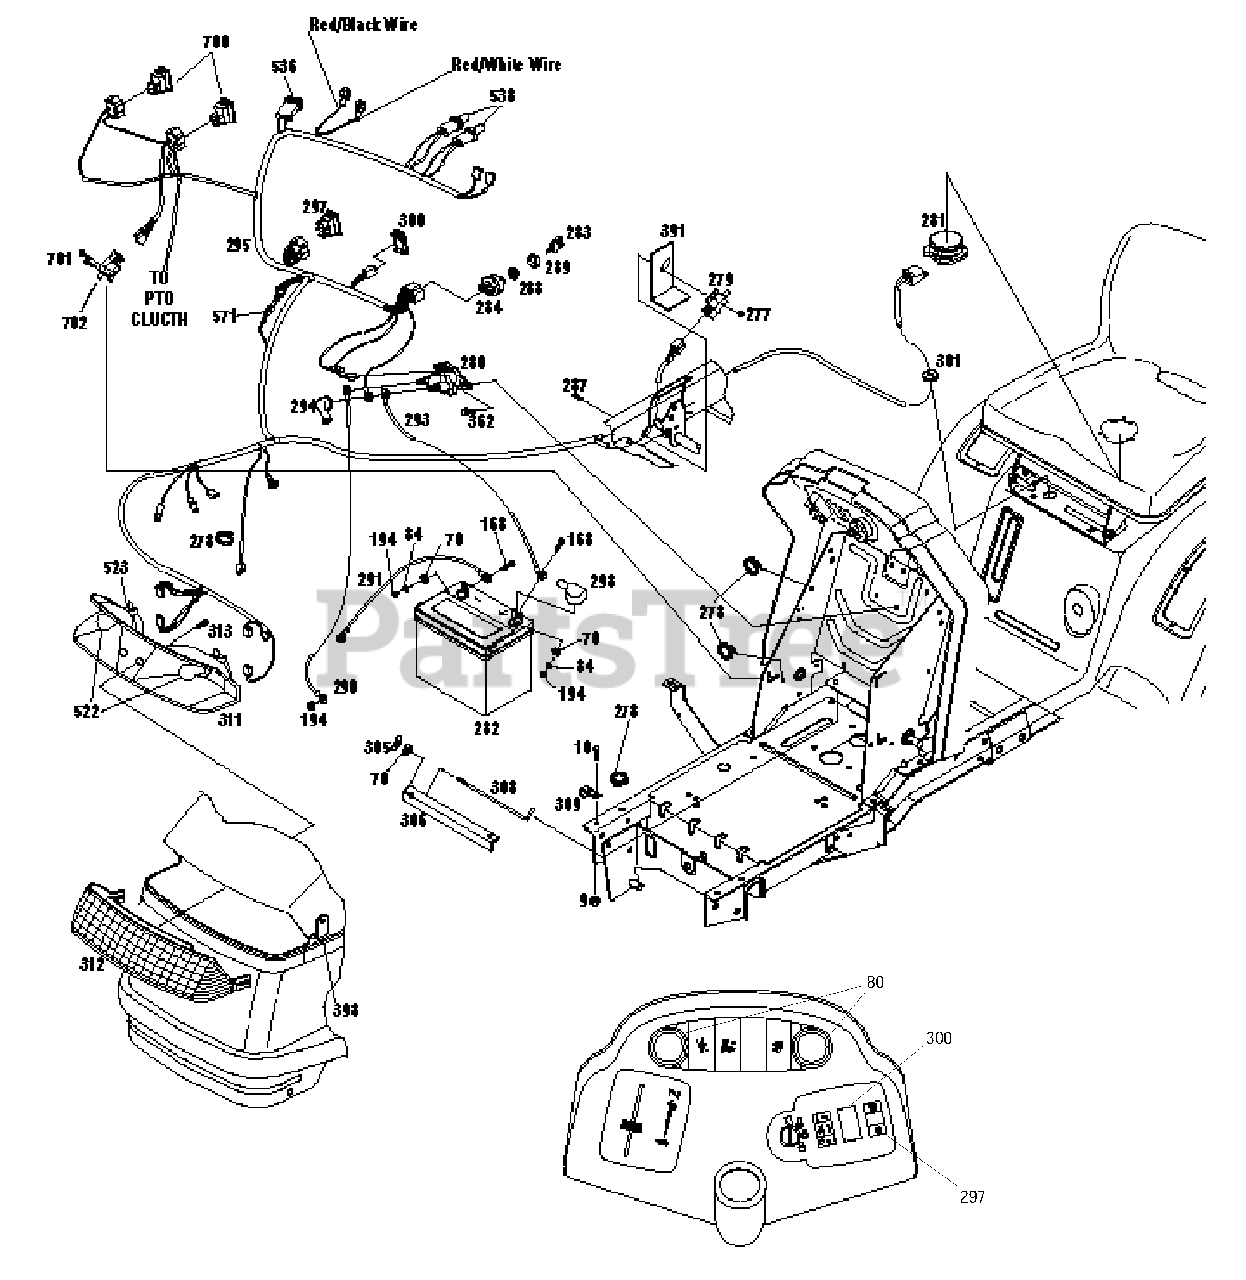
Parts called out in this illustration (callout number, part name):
9	Flange Nut, 5/16-18
10	Hex Head Screw, 5/16-18 x 3/4
70	Flat Washer, 1/4
84	Lockwasher, 1/4 SAE
168	Hex Head Screw, 1/4-20 x 3/4
194	Hex Nut, 1/4-20
277	Keps Nut, #10-24
278	Cable Tie
279	Push-Button Switch
280	Solenoid
281	Seat Switch
282	Battery
284	Ignition Switch
287	Sems Screw, #10-24 x 5/8
288	Ignition Switch Mounting Nut
289	Cap
290	Starter Cable
291	Negative Battery Cable
293	Battery Cable
294	Solenoid Boot
295	Main Harness
297	PTO Switch
298	Terminal Boot
300	Switch Cover
305	Wing Locknut, 1/4-20
306	Battery Clamp
308	Hook Bolt
311	Headlight Reflector
313	Self-Threading Screw
362	Self-Tapping Screw, 1/4-20 x 1/2
391	Switch Bracket
522	Headlight Bulb
536	Fuse
538	Panel Light Bulb
700	Relay
701	Tap Screw, #10-16 x 5/8
702	Safety Switch
